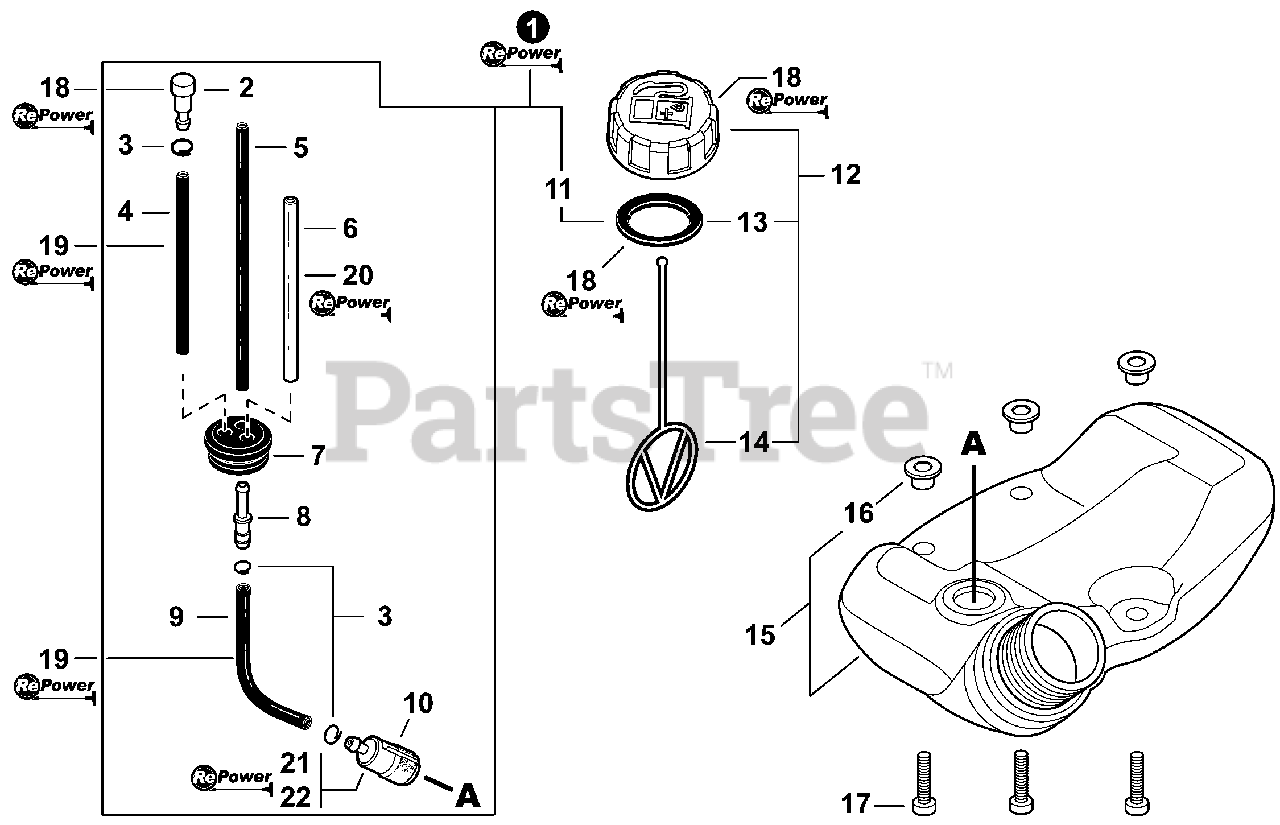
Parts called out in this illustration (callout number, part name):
1	FUEL SYSTEM KIT - REPOWER
2	VENT ASSY
3	CLIP Ø6
4	PIPE, FUEL 3×5×90 BLACK
5	PIPE, FUEL 3×5×74 BLACK
6	PIPE, FUEL 3×6×80 CLEAR
7	GROMMET, FUEL Ø5
8	CONNECTOR, PIPE Ø5ר3.5
9	PIPE, FUEL 3×5×130 BLACK
10	FILTER, FUEL
11	GASKET, FUEL CAP
12	CAP ASSY, FUEL
13	GASKET, FUEL CAP
14	CONNECTOR, CAP L= 123
15	TANK ASSY, FUEL
16	COLLAR 5
17	BOLT, TORX 5×20
18	CAP/VENT KIT - REPOWER
19	PIPE, BULK - REPOWER 3×5mm BLACK
20	PIPE, BULK - REPOWER 3×6mm CLEAR
21	TUNE-UP KIT - REPOWER
22	FILTER KIT - REPOWER
